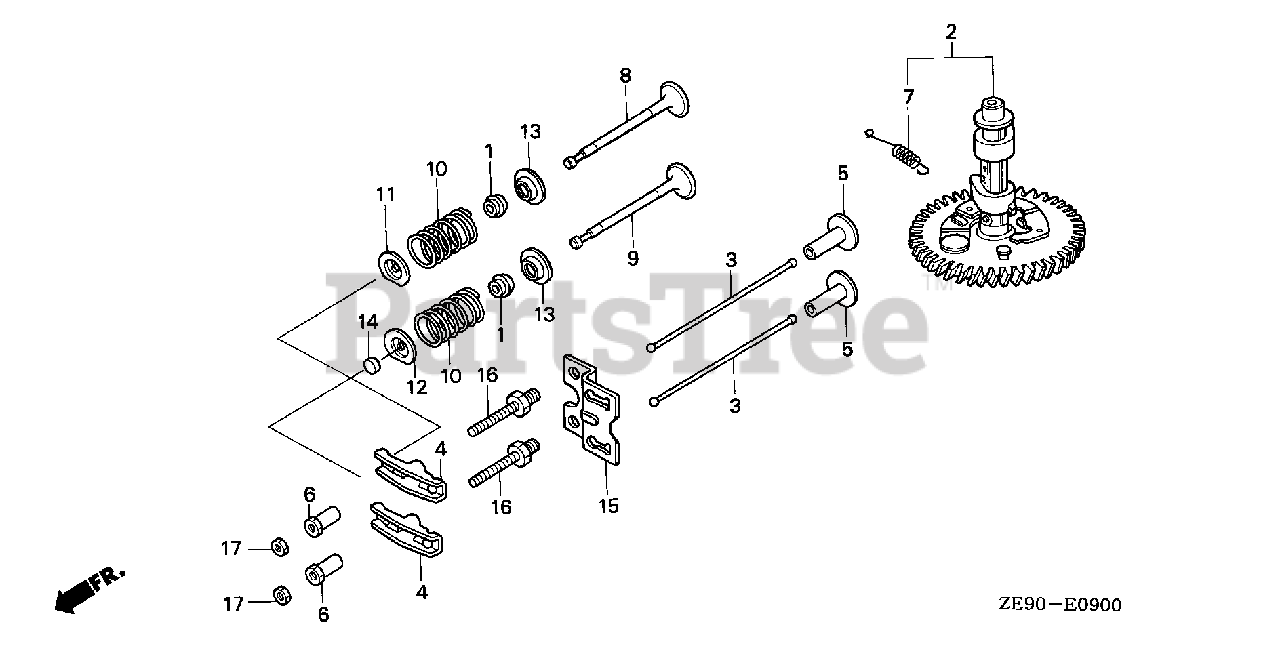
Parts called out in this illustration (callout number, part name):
1	SEAL, VALVE STEM
2	CAMSHAFT ASSY. (NOT AVAILABLE)
4	ARM, VALVE ROCKER
5	LIFTER, VALVE
6	PIVOT, ROCKER ARM
7	SPRING, WEIGHT RETURN
8	VALVE, IN. (STELLITE)
9	VALVE, EX. (STELLITE)
10	SPRING, VALVE
11	RETAINER, IN. VALVE SPRING
12	RETAINER, IN. VALVE SPRING
13	SEAT, VALVE SPRING
15	GUIDE, PUSH ROD
16	BOLT, PIVOT (8MM)
17	NUT, PIVOT ADJUSTING
